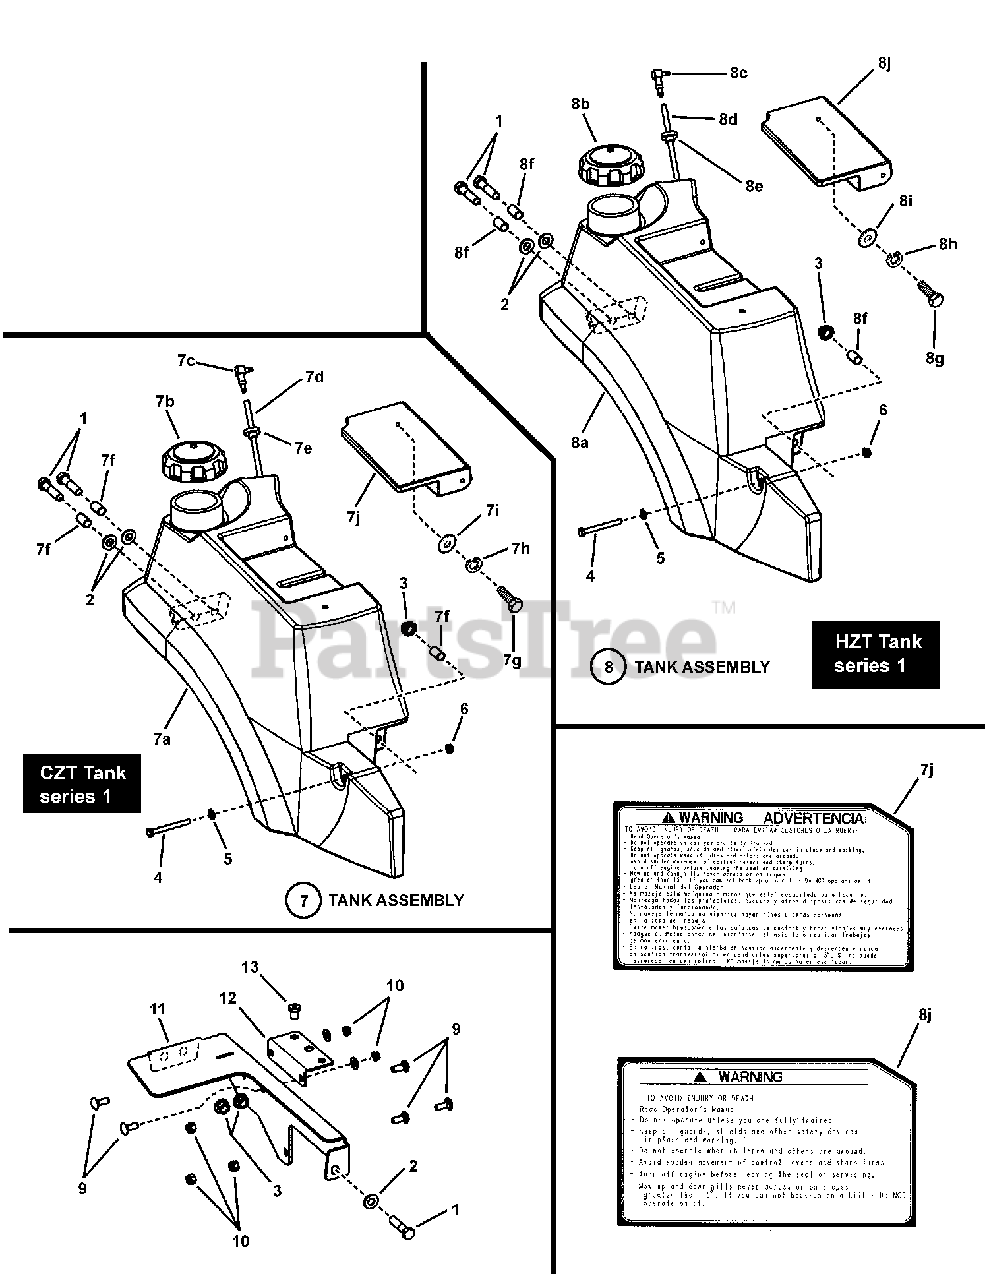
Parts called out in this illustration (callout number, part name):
1	SCREW, 7/16-14 x 2" Hex Head Cap, GR 5
2	WASHER, 1/2" Flat SAE
3	NUT, 7/16-14 HEX NYLON LOCK
4	BOLT, 5/16-18 X 2-1/2" GD5 YZ
5	WASHER, 5/16" Flat
6	NUT, 5/16-18 HEX NYLON LOCK
7	ASSEMBLY, R.H. Tank CZT (incl. 10 items shown below)
8	ASSEMBLY, R. H. Tank HZT (incl. 10 items shown below)
9	BOLT, 3/8-16 x 1" Square Neck Carriage, GR 5
10	NUT, 3/8-16 HEX NYLON LOCK
11	WELDMENT, R.H. Tank Bracket
12	BRACKET, Auxiliary Fuel Valve
13	WELL-NUT, 1/4-20 x 53/64
